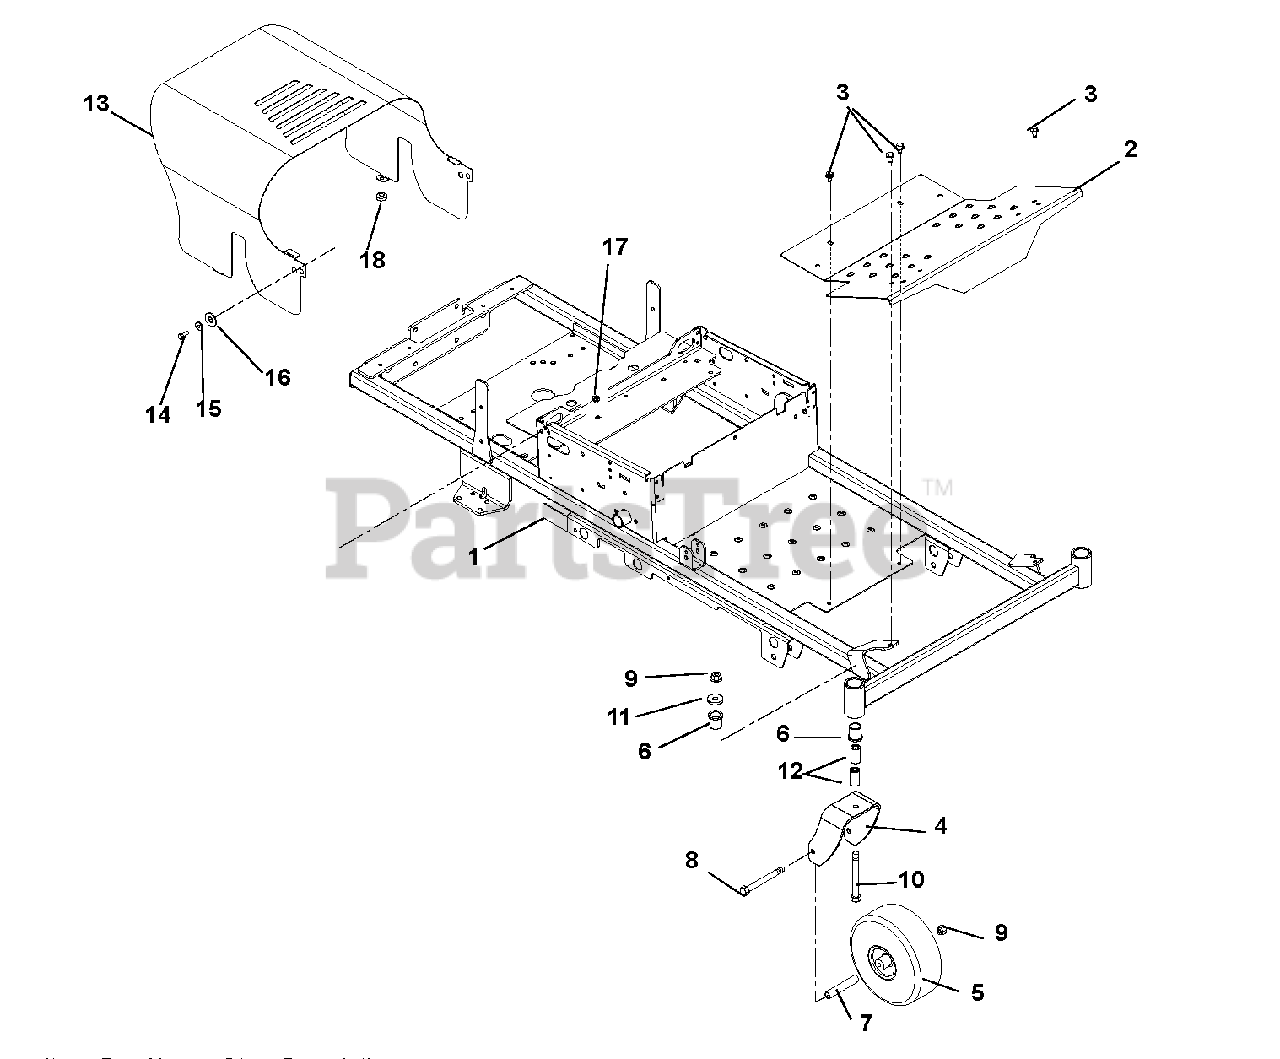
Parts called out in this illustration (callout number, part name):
1	Weldment, Frame
2	Footrest, MZ
3	Screw, Tapping .31-18 x .50
4	Fork, Caster
5	Wheel/Tire Assembly, 11.0 x 4.0 x 5.0, Monitor
6	Bushing, Flange 1.00 x 1.25 x 1.50 x 1.50
7	Spacer, Wheel
8	Bolt, Hex .50-13 x 6.50 Grade 5
9	Nut, .50-13 Nyloc Flange
10	Bolt, Hex .50-13 x 5.00 Grade 5
11	Washer, Flat Steel .511 x 1.441 x .125
12	Spacer, Caster
13	Hood, 1734 ZTXL
14	Bolt, Hex .25-20 x .75 Grade 5
15	Bushing, Flange .265 x .437 x .250 x .750
16	Washer, Flat Steel .50 x 1.25 x .083
17	Nut, Locking Top Flange .25-20
18	Button Bumper
